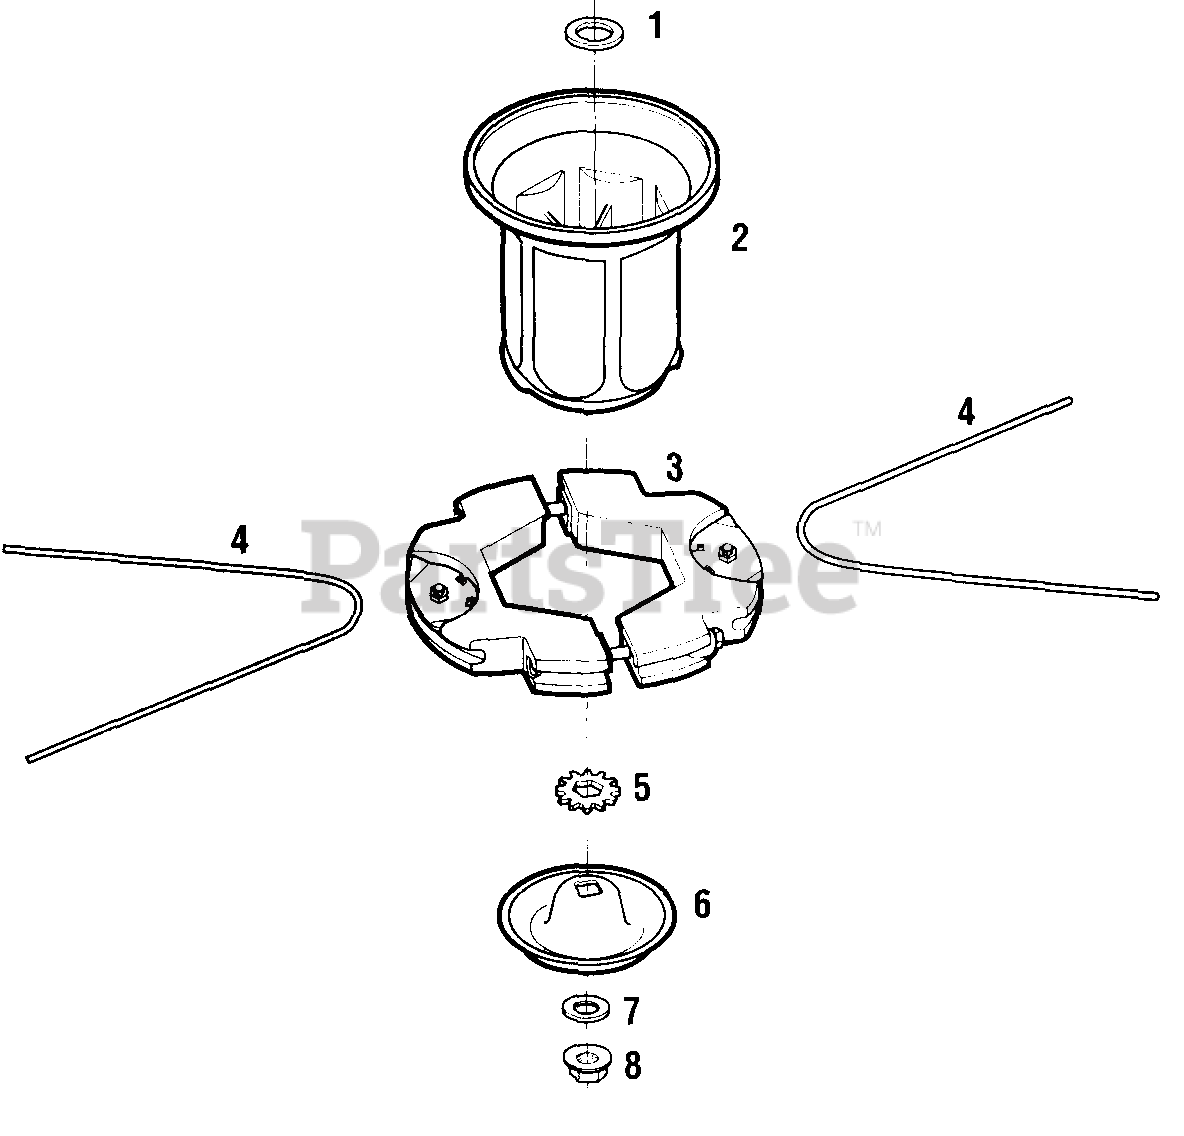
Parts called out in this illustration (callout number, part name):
1	Shoulder Washer
2	Spindle Head
3	Trimmer Head
4	Trimmer String
5	Hex Spline Washer
8	Hex Flange Nut, 1/2-13
